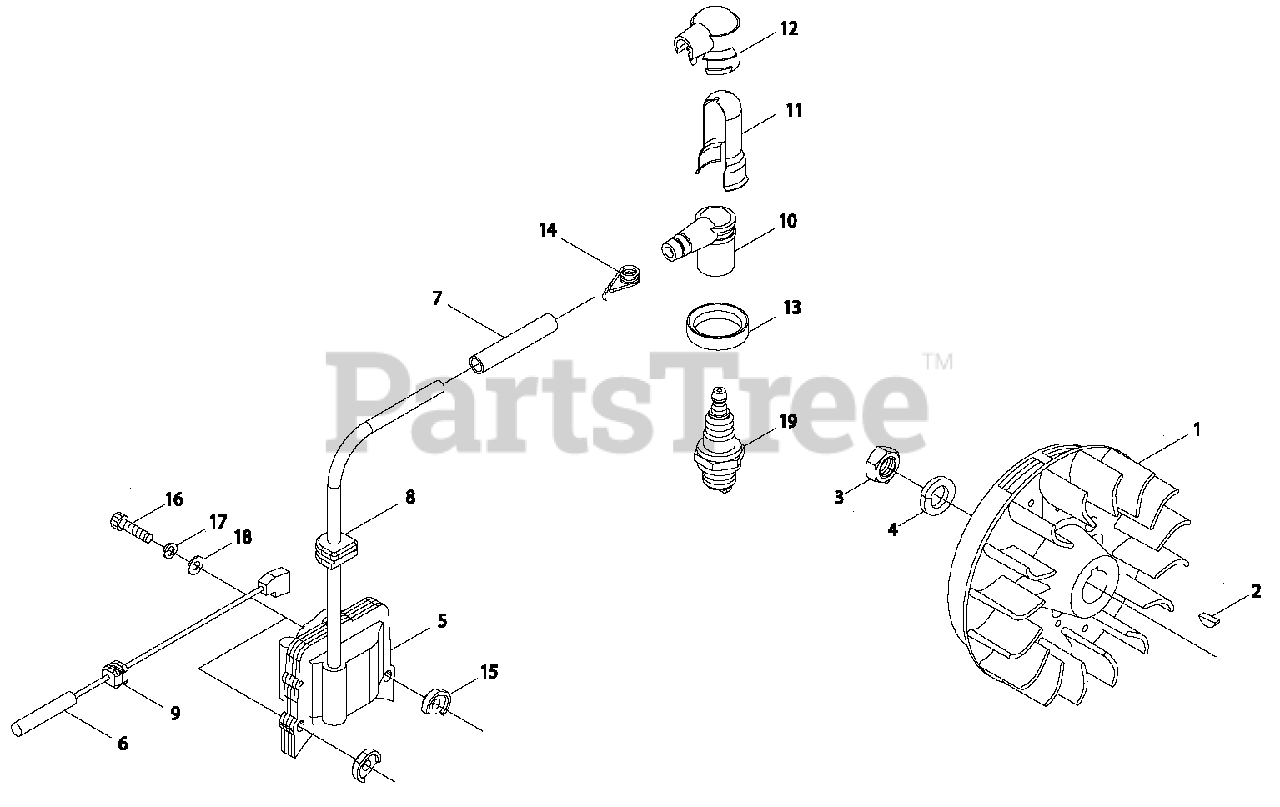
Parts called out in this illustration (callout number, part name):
1	FLYWHEEL
2	KEY - 3X10
3	NUT - 10
4	LOCKWASHER - 10
5	COIL, IGNITION
6	LEAD - IGNITION
7	TUBE
8	GROMMET
9	GROMMET
10	CAP, SPARK PLUG
11	SHIELD
12	COVER, CAP
13	SEAL, DUST
14	TERMINAL, SPARK PLUG CAP
15	INSULATOR
16	BOLT - 4X24
17	LOCKWASHER - 4
18	WASHER
19	SPARK PLUG -- BMR-6A
